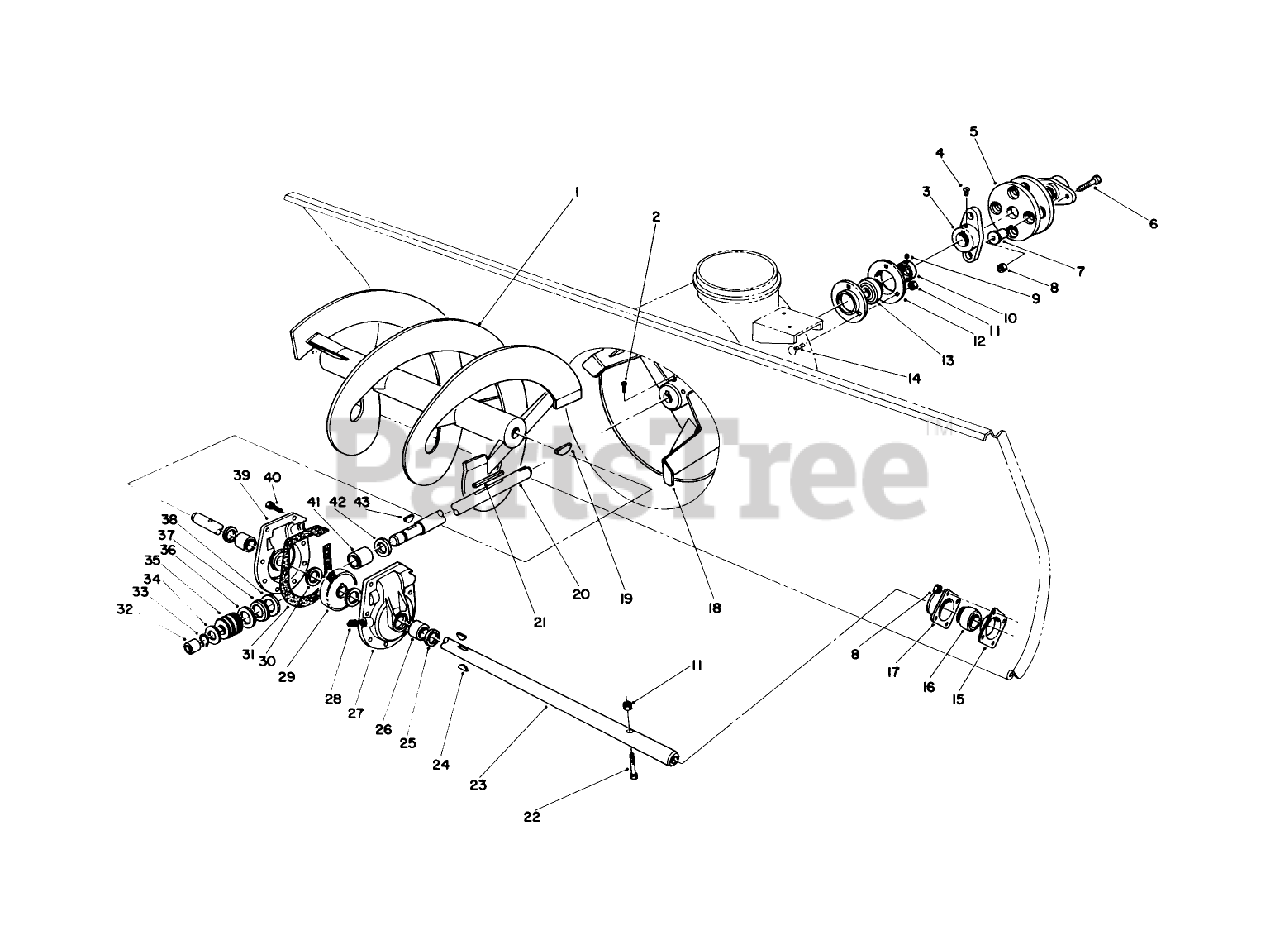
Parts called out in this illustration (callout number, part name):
1	Auger RH
2	SCREW-SET, SQH
3	HUB WA (KEY) R
4	SCREW-SET
5	COUPLING-RUBBER
6	SCREW-HH
7	SPACER-COUPLING, RUBBER
8	NUT-LOCK, NI
9	SCREW-HSH
10	EXT LOCKING COLLAR
11	NUT-LOCK, NI
12	BRG FLANGE
13	BALL BRG W/COLLAR
14	BOLT-CARR
15	BEARING-FLANGE, REAR
16	BEARING
17	BEARING-FLANGE, FRONT
18	IMPELLER ASM
19	KEY-WOODRUFF
20	IMPELLER SHAFT
22	SCREW-HH
23	SHAFT-AUGER
24	KEY-WOODRUFF
25	SEAL-OIL
26	BUSHING
27	Gear Case & Bushing Assy. (Incl. Ref. #25 & 26)
28	PLUG-PIPE, SQH
29	GEAR-WORM, 27T
30	WASHER-THRUST
31	GASKET-CASE, GEAR
32	BUSHING
33	Ring-Snap
34	WASHER-THRUST
36	THRUST-WASHER
37	BEARING-THRUST
38	WASHER-THRUST
39	Gear Case & Bushing Assy. (Incl. Ref. #25 & 26)
40	SCREW-TAPTITE
41	BUSHING-SPECIAL
42	RING-QUAD
43	KEY-WOODRUFF
